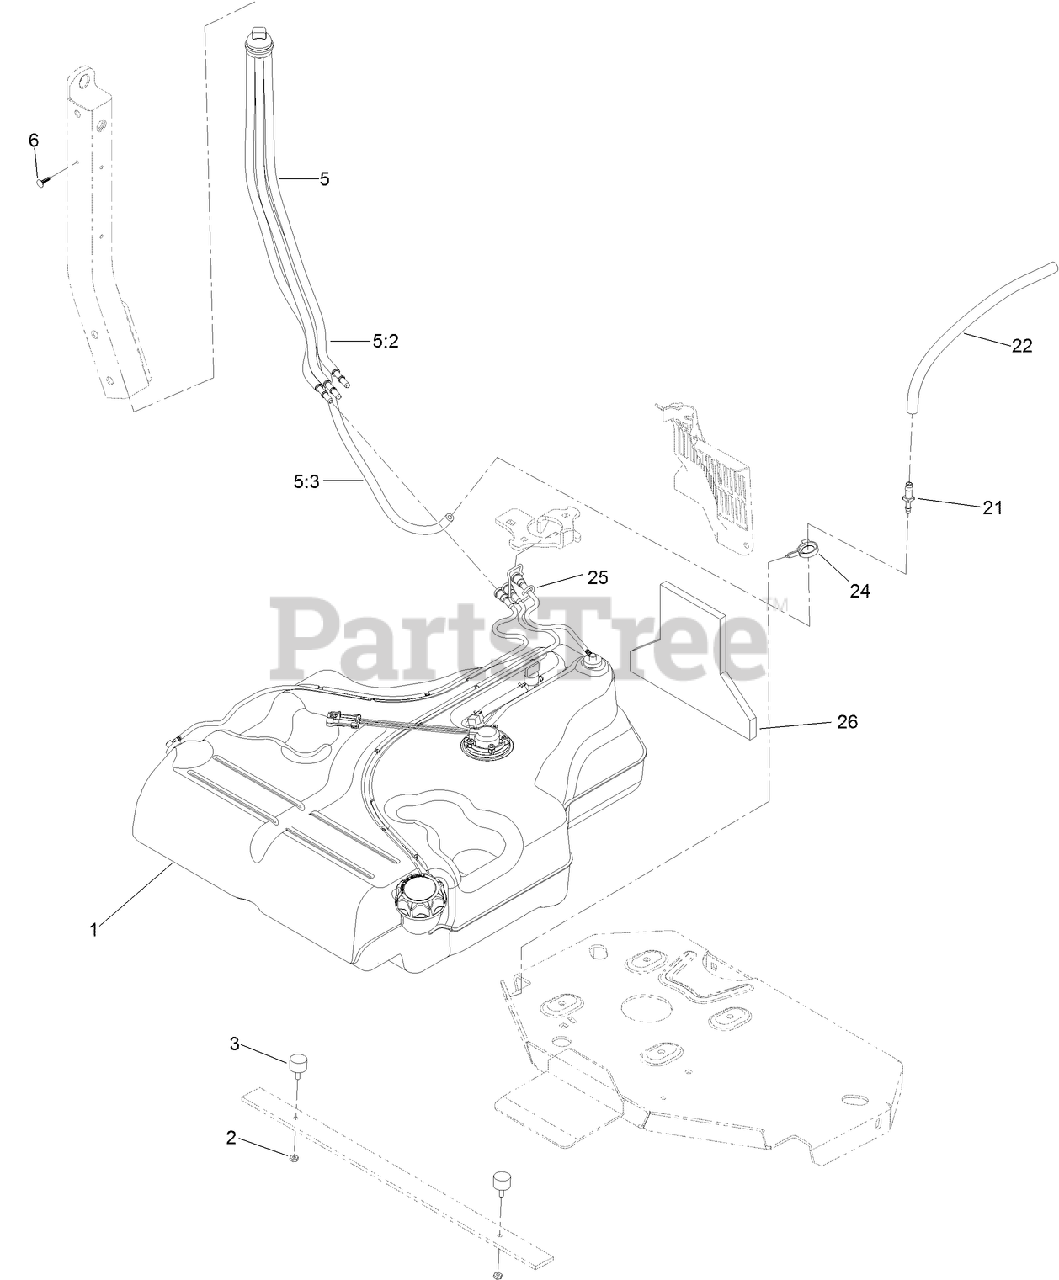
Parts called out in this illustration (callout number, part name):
1	FUEL TANK ASM
2	NUT-JAM
3	BUMPER-RUBBER (W/ STUD)
5	FUEL MANIFOLD VENT ASM
5:2	HOSE-FUEL
5:3	HOSE-FUEL
6	PLUG-PLASTIC
21	FITTING-STRAIGHT
22	HOSE-FUEL
24	CLAMP-HOSE
25	RETAINER-LINE, VAPOR
26	INSULATION-FOAM, FUEL TANK
